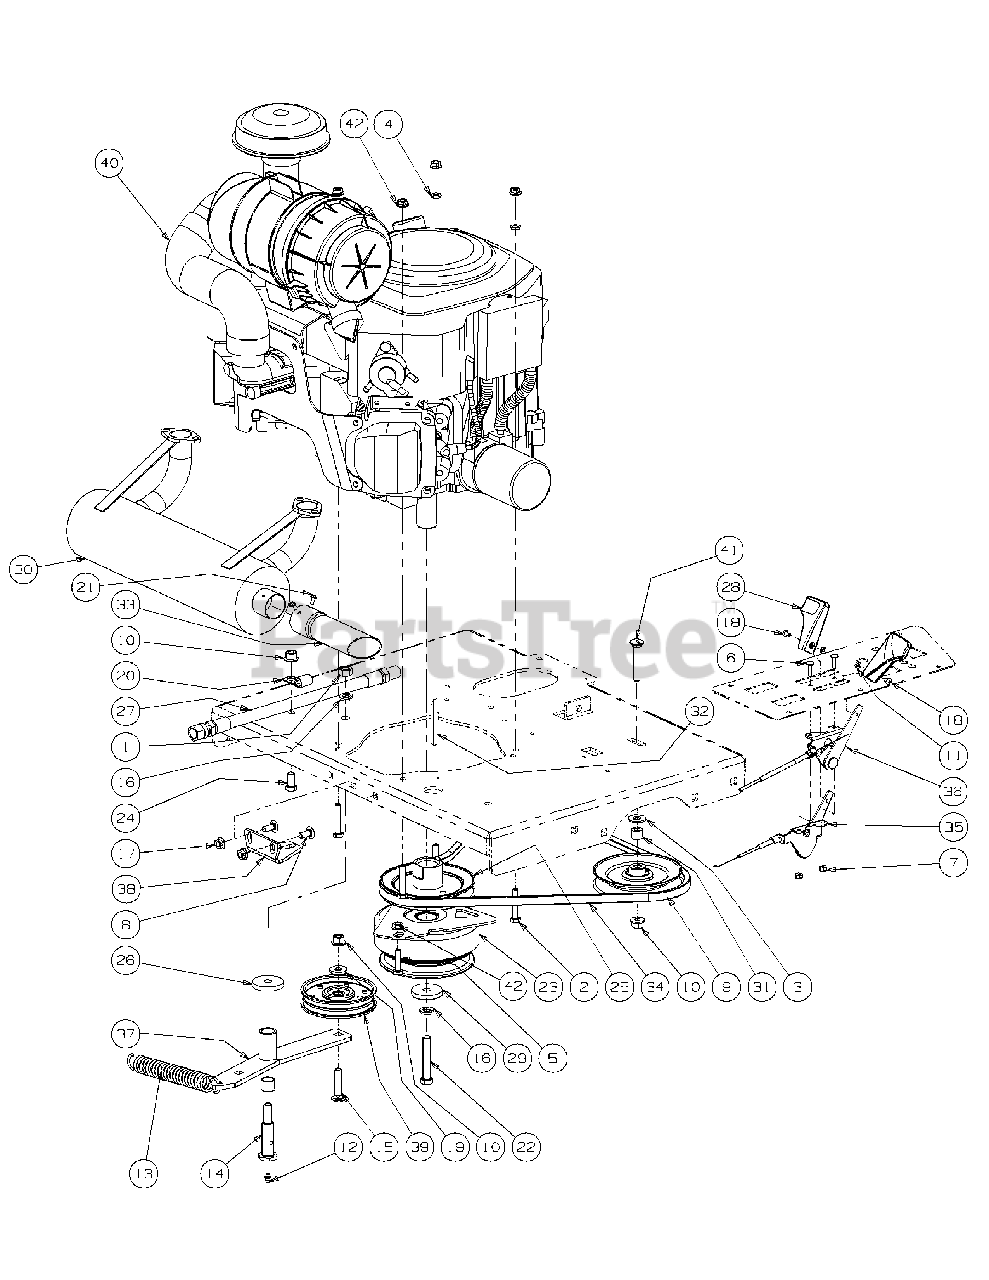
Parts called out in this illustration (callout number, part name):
1	Hex Nut, 7/16-14
2	HHCS, 5/16-18, 1-3/4
3	Flat Washer, 3/8 zinc
4	Flat Washer, .320 ID x .591 OD x .078
5	HHCS, 5/16-18 x 1-1/4
6	Round Hd. Machine Screw, 10-32 x 3/4
7	Lock Nut, Nylon Insert, 10-32
8	Carriage Bolt, 5/16-18 x .75
9	Idler Pulley
10	Flange Lock, Hex Nut, 3/8-16
11	Nut Washer, W/Star, 8-32
12	Grease Fitting, 1/4-28 x 3/16
13	Spring Extension, 1.0 OD x 5.00S
14	Shoulder Screw, 7/16-14
15	Hex Carriage Screw, 3/8-16, 1.75
16	Lock Washer, 7/16
17	Hexflange Lock Nut, 5/16-18
18	Machine Screw, 8-32, .375
19	Flat Washer, .406 ID, 1.0 OD, .105
20	Clip, Heat Shield Cable
21	Screw, #8-32 x 0.375
22	Capscrew, 7/16-20 x 2.50
23	Clutch Brake, 1.125 ID
24	Hex Cap Screw, 3/8-16, .750
25	Pump Drive Pulley
26	Flat Washer, 7/16 ID x 1.75 OD x .25
27	Oil Drain Hose
28	Control Throttle Knob
29	Flat Washer, 7/16 ID x 1.75 OD x .25
30	Muffler Accessory Kohler
31	Spacer, 1.50 OD x .385 ID x .585
32	Key, 1/4 x 1/4 x 2.75
33	Exhaust Pipe
34	Belt, 50.125 Lg
35	Throttle, Control Cable
36	Choke, Control Cable
37	Engine Idler Arm Assembly Includes:
38	Retainer Clutch Assembly
39	Flat Pulley with Flanges
40	Engine, 23HP Kohler
41	Carriage Bolt, 3/8-16 x 2.25
42	Nut, 5/16-18, Flangelock
